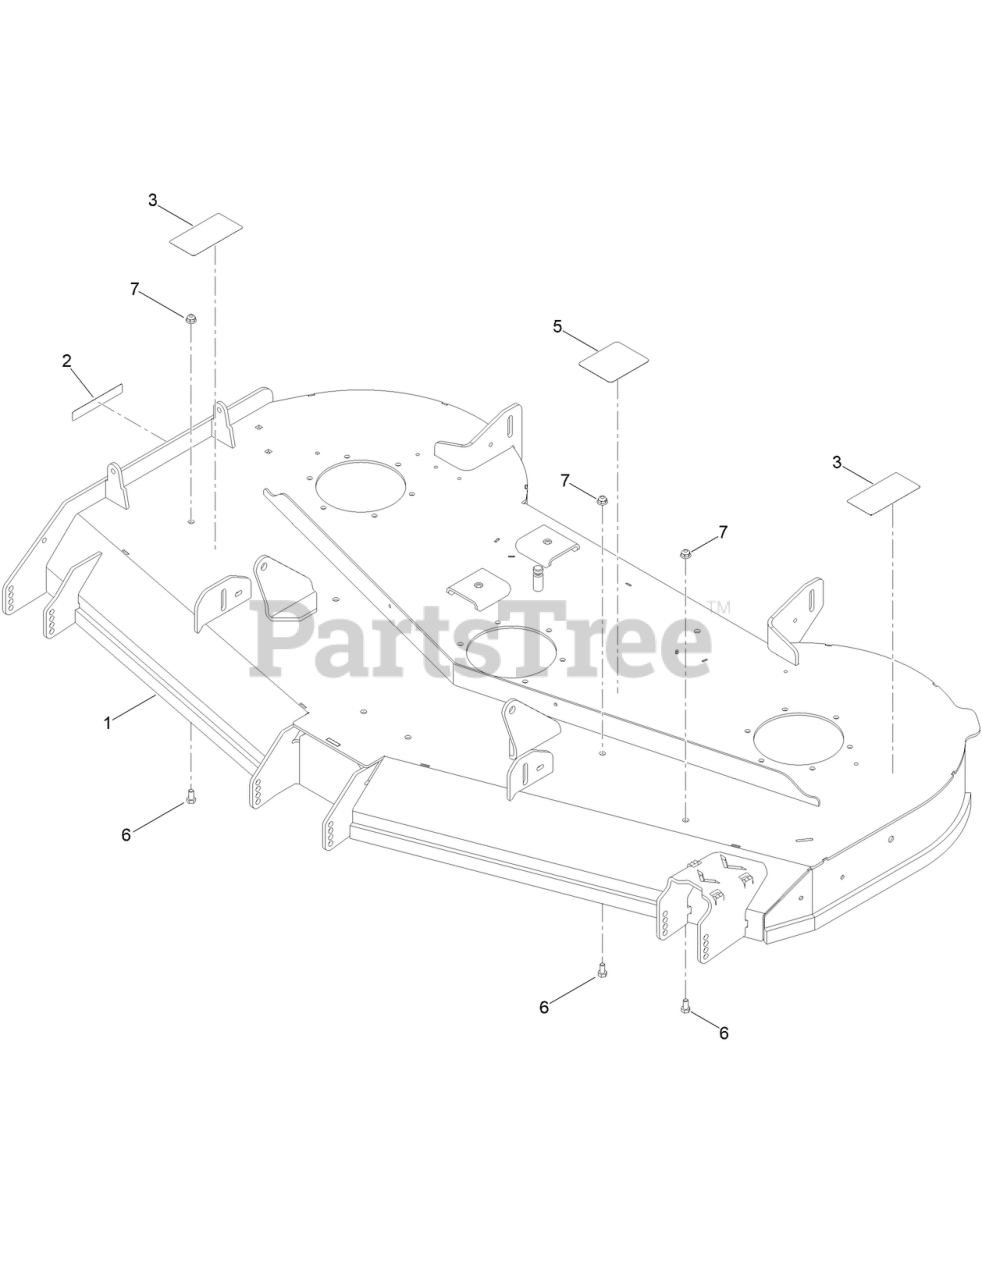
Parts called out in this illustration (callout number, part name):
2	DECAL-DANGER
3	DECAL-DANGER, DECK
5	DECAL-BELT ROUTING
6	SCREW-HH
7	NUT-HF
